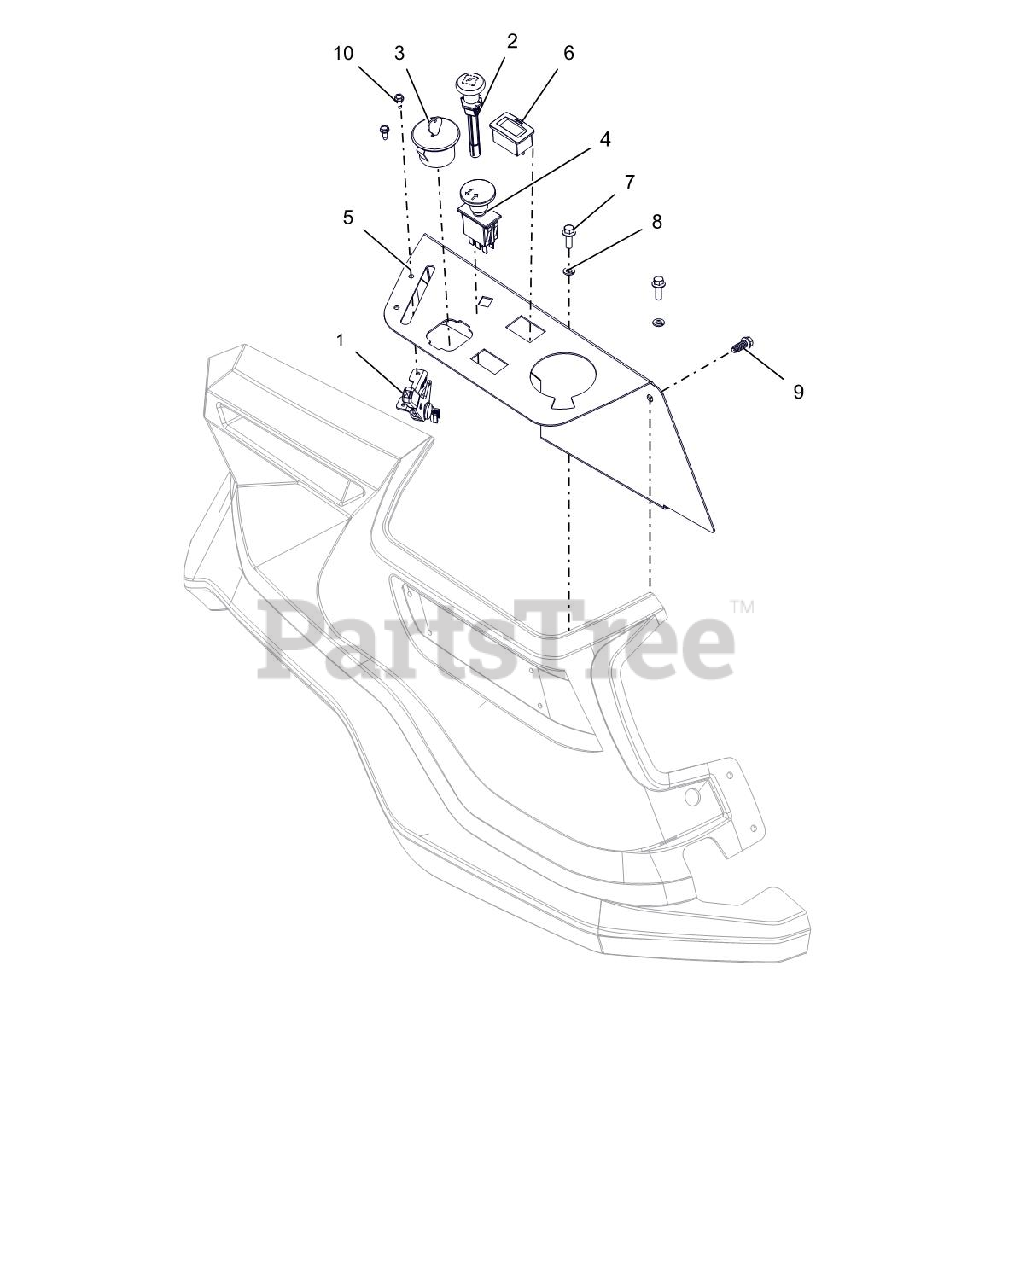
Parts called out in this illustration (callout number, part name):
1	CABLE - THROTTLE CONTROL
2	CABLE - CHOKE, SNAP-IN
3	KEYSWITCH-IGNITION 3 POS
4	SWITCH, CLUTCH (YELLOW)
5	PANEL, RIGHT SIDE FENDER MOUNT
6	HOUR METER
7	BLT,HEX-FLG .25-20X.75 G5 BFP
8	@WSHR-LK .25X.062 REG YWZC
9	SCR-.312X.75 #14H H/W/H H/L CZ
10	@SCR-TAP 10-24X.50 HWH TR YWZC
